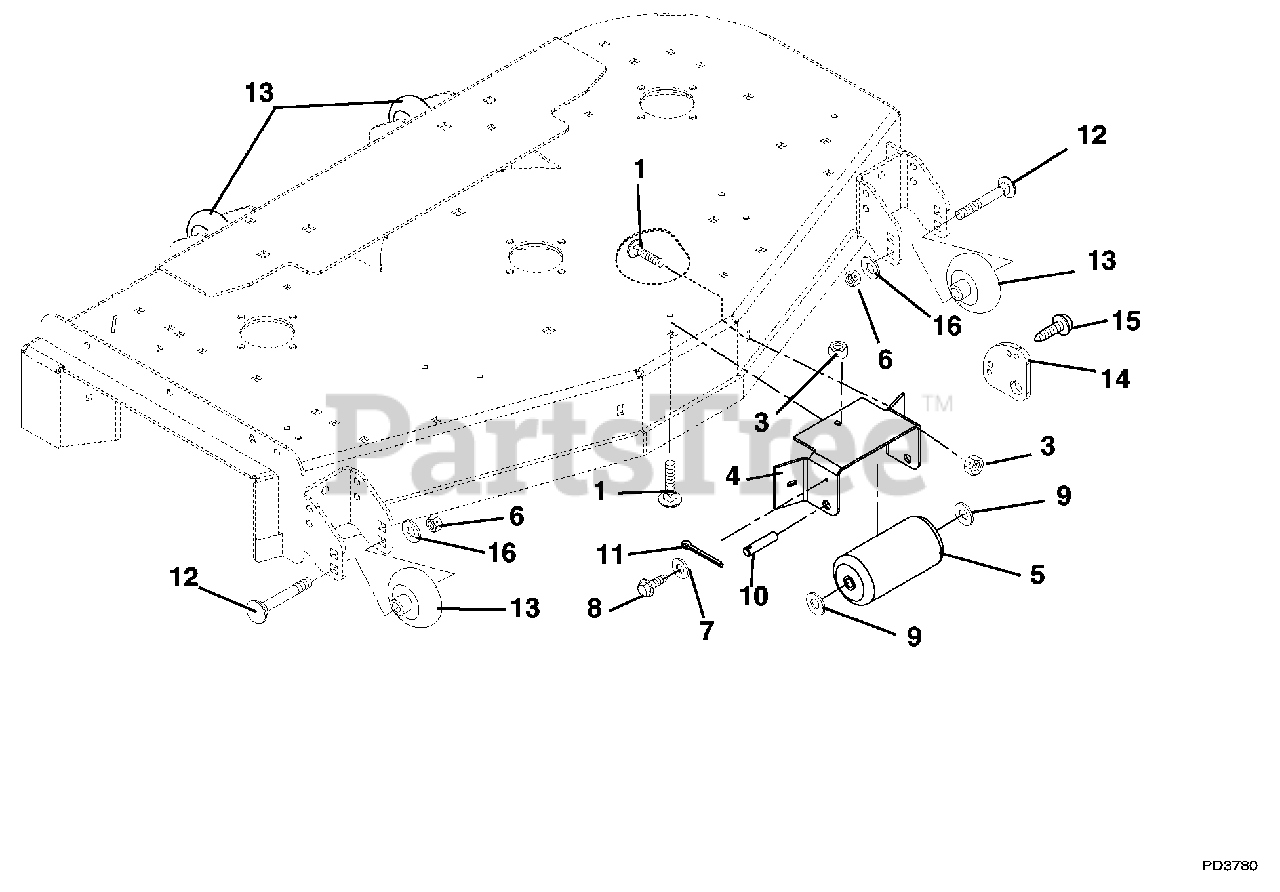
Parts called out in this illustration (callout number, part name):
1	Bolt, Round Head Square Neck .38-16 x 1.00 Grade 5 (042, 043, 044, 054, 310, 311)
2	Bolt, Round Head Square Neck .38-16 x 1.25 Grade 2 (051, 055)
3	Nut, Locking Top Flange .38-16
4	Bracket, Anti-Scalp Roller
6	Nut, Locking Nylon .50-13
7	Washer, Flat Steel .281 x .62 x .065
8	Screw, Tapping .25-20 x .75 Hex Washer Head
9	Washer, Flat Steel .656 x 1.31 x .095
11	Pin, Cotter .25 x 2.0
12	Bolt, Round Head Square Neck .50-13 x 5.00 Grade 2
13	Wheel, 3 x 5
14	Anti-Scalp Washer
15	Screw, Tapping .25-20 x .62 Hex Washer Head
16	Washer, Flat Steel .531 x 1.06 x .095
